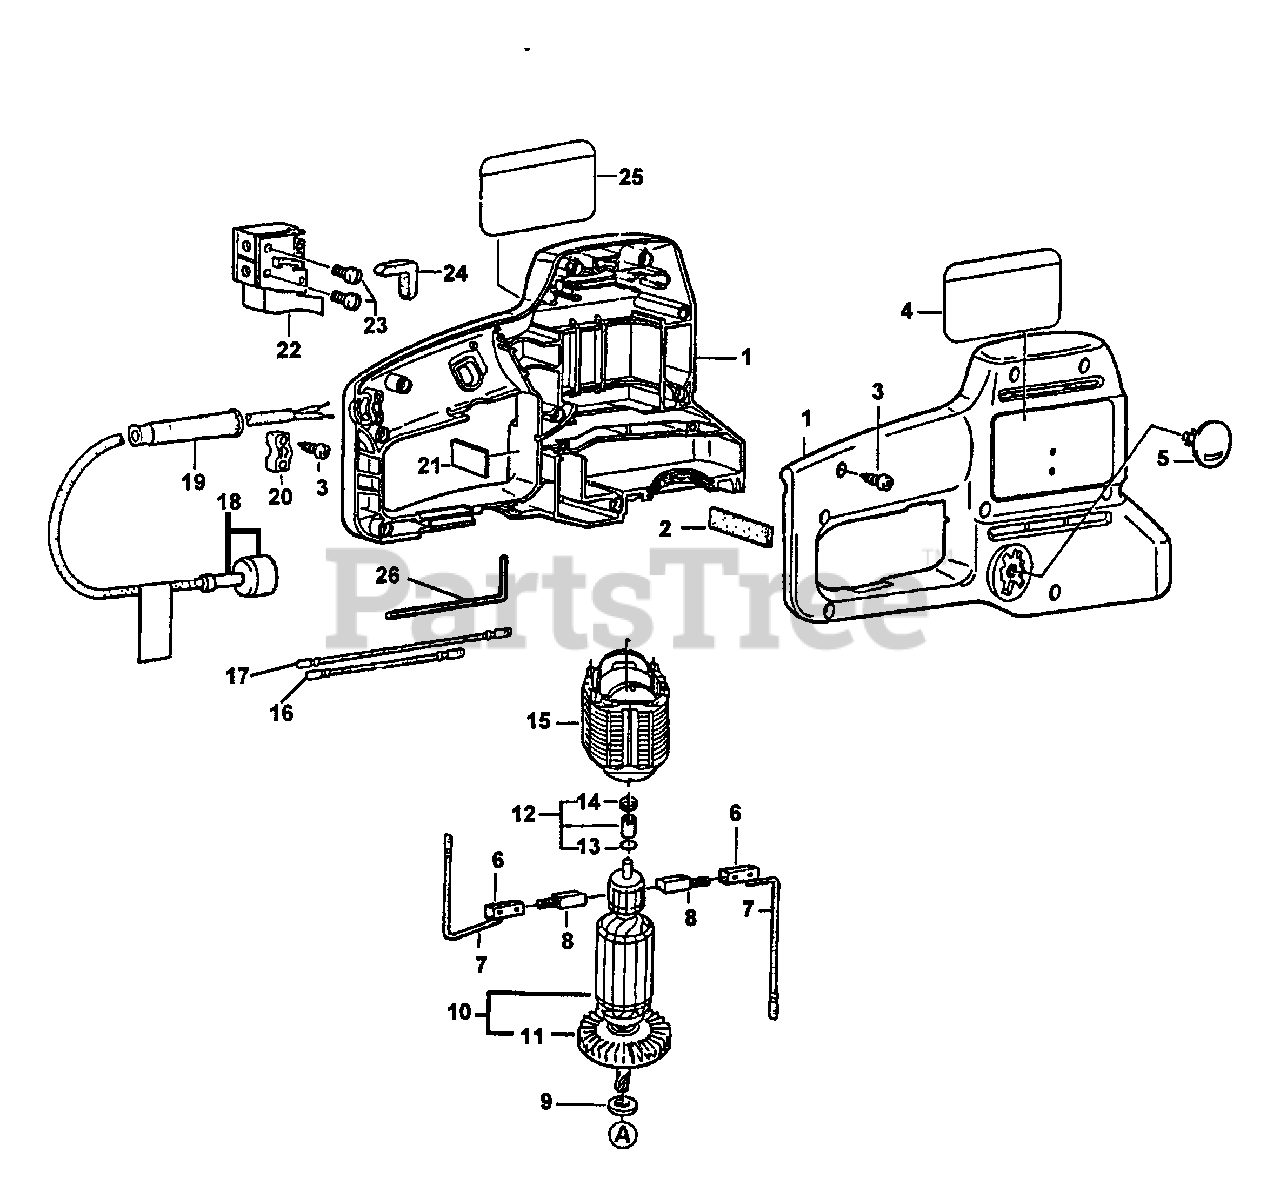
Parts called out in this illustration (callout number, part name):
1	HOUSING, MOTOR
2	PACKING, FELT
3	SCREW 4×16
4	LABEL, ECHO
5	KNOB
6	HOLDER, BRUSH
7	CABLE 80 MM
8	BRUSH SET
10	ARMATURE - 115V
11	FAN
12	BUSHING ASSY
13	PACKING, FELT
14	O-RING
15	FIELD 115V
16	CABLE 100 MM
17	CABLE 200 MM
18	CORD (115V)
19	RELIEF, STRAIN
20	CLAMP, CORD
21	LABEL, WARNING
22	SWITCH, ON-OFF
23	SCREW
24	STRIP, SEAL
25	LABEL, ECHO EHC-3000
26	WRENCH, ALLEN
